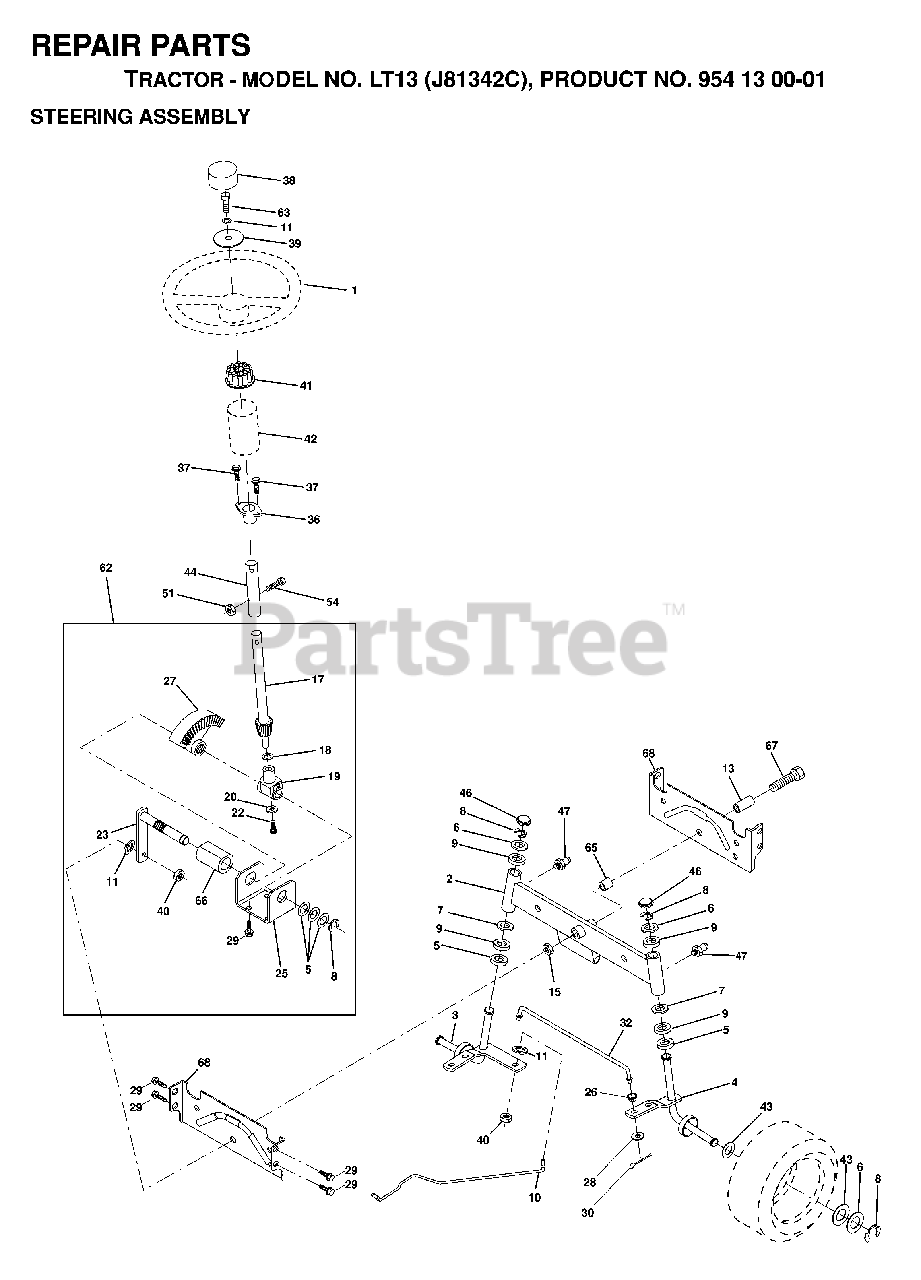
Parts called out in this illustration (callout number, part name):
2	AXLE ASSY
3	SPINDLE ASM LH
4	SPINDLE ASM RH
8	RING CLIP
9	BRNG T
10	DRAGLINK-STAMPED
11	WASHER, LOCK 3/8
13	BEARING AXLE
15	NUT-LOC,FLANGE LT
17	SHAFT ASM STEERING
18	THRUST WASHER
19	SHAFT,SUPPORT
20	WASHER
22	SCREW HEX SOCKET 1/4-20 X 5/8
23	SHAFT PITMAN
25	BRACKET STEERING
26	BUSHING.DRAGLINK
27	GEAR.SECTOR
28	WASHER
29	SCREW
30	COTTER PIN
32	TIE ROD
36	BUSHING, STEERING
38	RP INSERT
39	WASHER T
40	GRIPCO NUT
41	ADAPTER LT
42	STEERING BOOT, GRAY
44	EXT SHAFT STEERING
46	CAP.SPINDLE
47	ZERK M
51	NUT.71038.31-18.HEX.NYLOCK
54	BOLT.5/16-18X1-1/4 FULL.THREAD
62	KIT, STEERING ASSEMBLY
65	SPACER AXLE
66	BEARING ARM
67	BOLT.HEX.FINISHED.5/8
68	AXLE, BRACE
